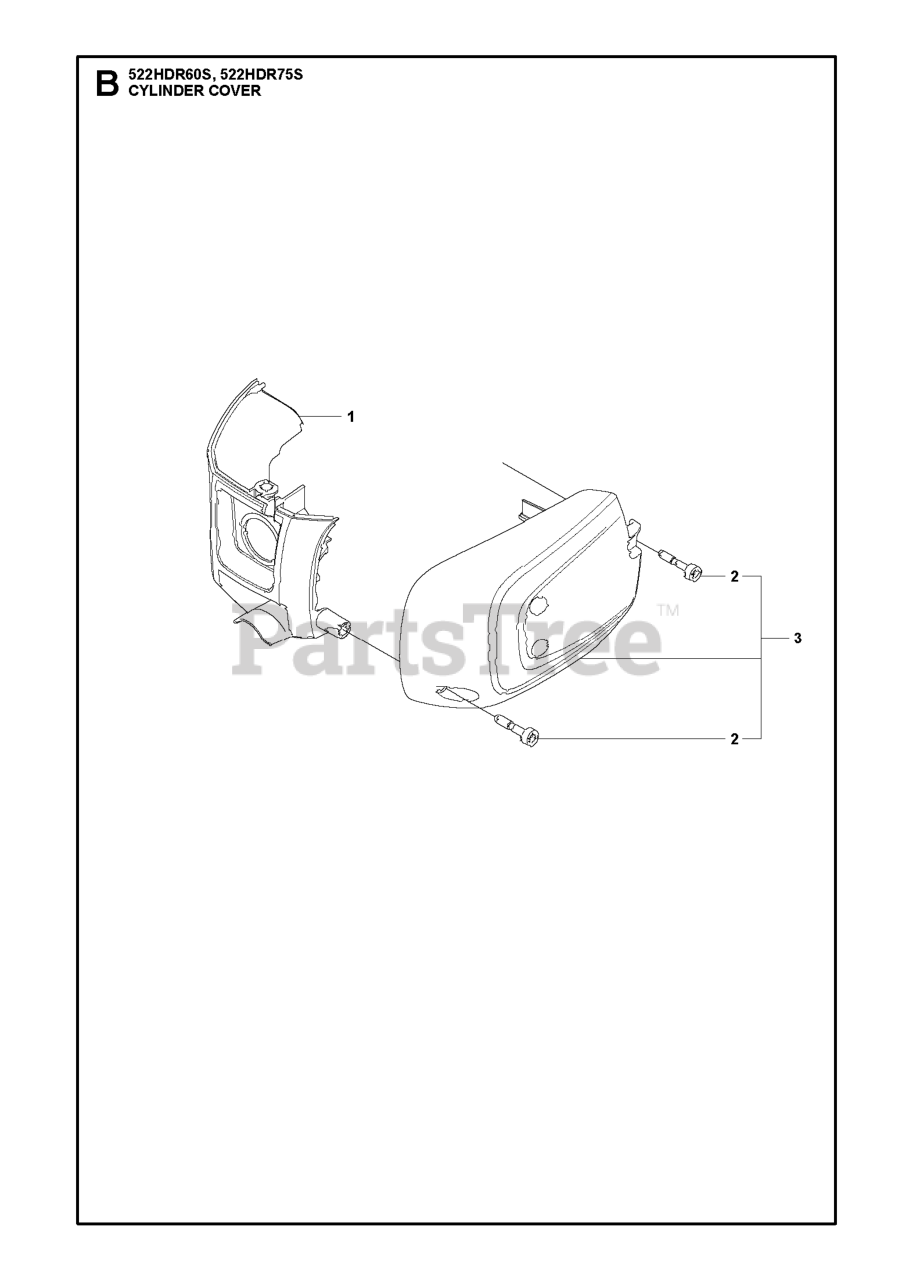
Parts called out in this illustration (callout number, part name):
1	CYLINDER COVER
2	SCREW CITXSCMO M5X25
3	HEAT PROTECTOR KIT 522
